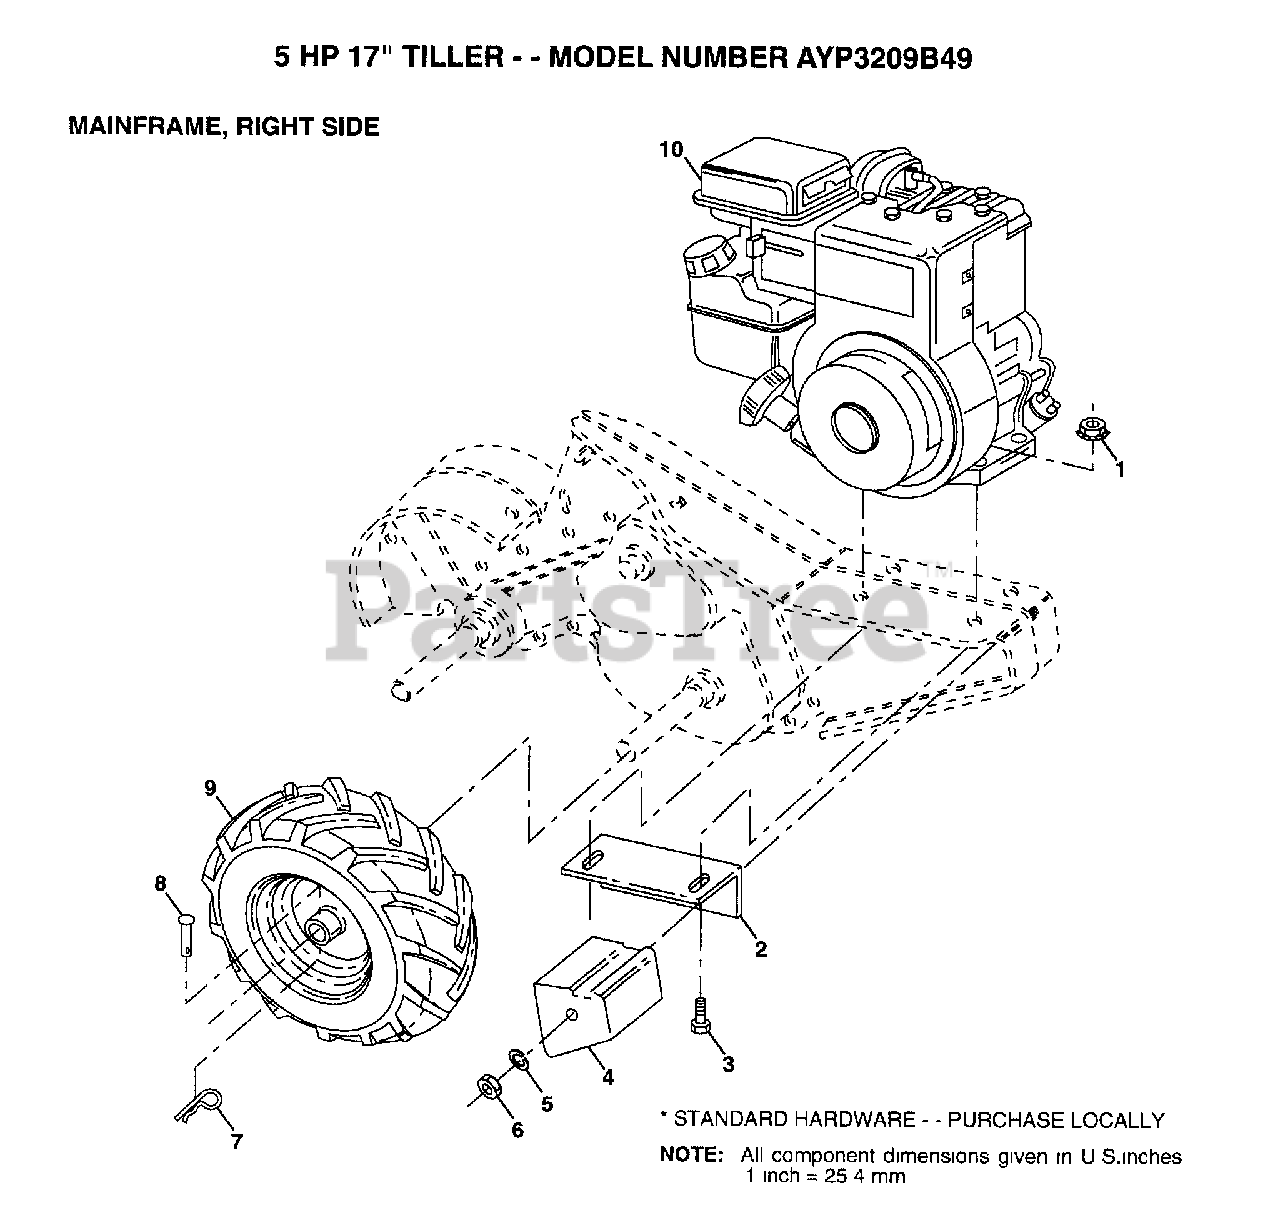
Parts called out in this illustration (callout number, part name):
2	BRACKET RH CRT
3	BOLT.HEX.5/16-1.5
4	COUNTERWEIGHT CRT
5	LOCKWASHER
6	NUT.HEX.3/8-16UNC
7	RETAINER M
8	RIVET.DRILL.1.75
9	TIRE TI
